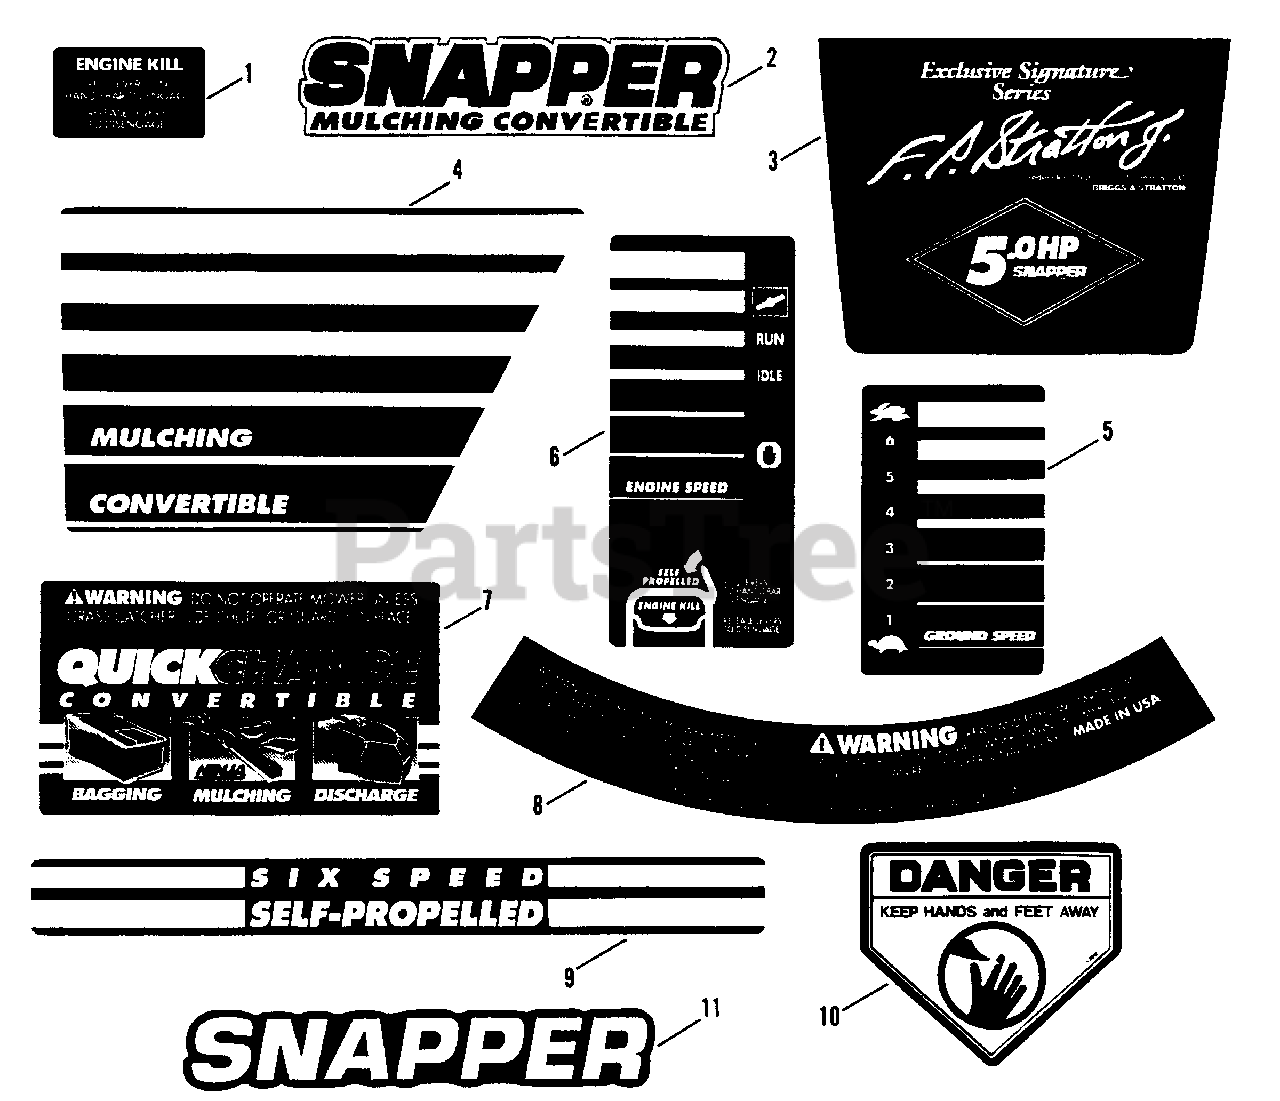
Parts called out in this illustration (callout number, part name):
1	DECAL, Engine Kill
2	DECAL - SNAPPER, Nameplate (Mulching Convertible)
3	DECAL, 5 HP Signature Series
4	DECAL, Mulching Convertible
5	DECAL, Ground Speed
6	DECAL, Engine Speed
7	DECAL, Quick Change Convertible
8	DECAL - WARNING
9	DECAL, Six Speed Self Propelled
10	DECAL-DANGER
11	DECAL - SNAPPER, Molded Logo (Chrome)
